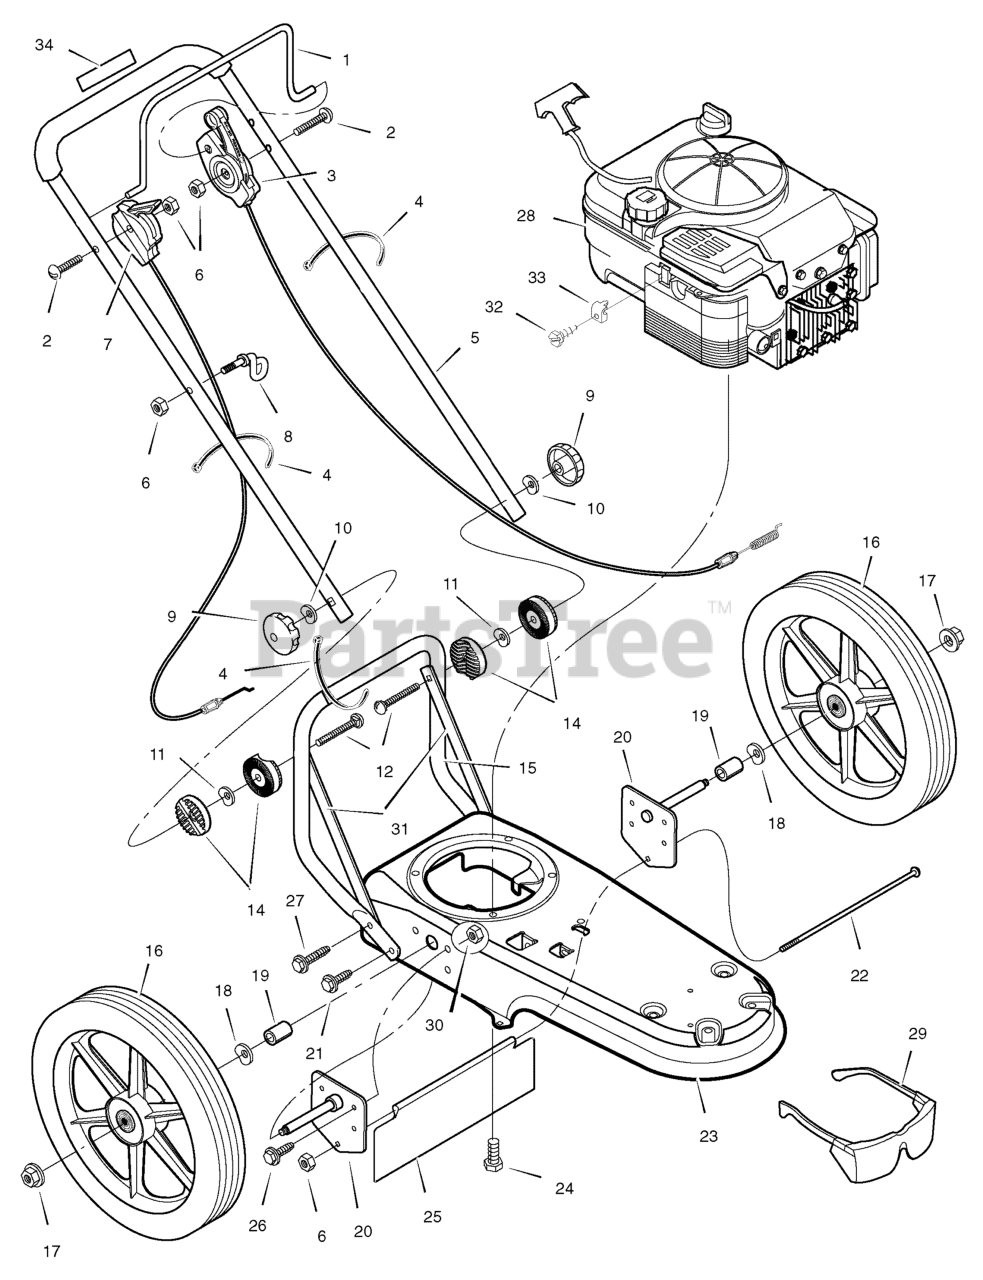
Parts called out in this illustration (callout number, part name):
1	LEVER, Stop
3	CABLE, Control Latching
4	TIE, Cable
7	CONTROL, Throttle
8	GUIDE, Rope
9	KNOB, Handlebar
11	WASHER, Spring
14	PIVOT, Handlebar
15	HANDLEBAR, Lower
16	WHEEL & TIRE
17	NUT, Axle
20	ASSEMBLY, Axle & Bracket
22	BOLT, Carriage
25	SHIELD, Trailing
28	ENGINE
29	PROTECTION, Eye
31	SUPPORT, Handle
33	CLAMP, Throttle
34	DECAL, Engine Stop
